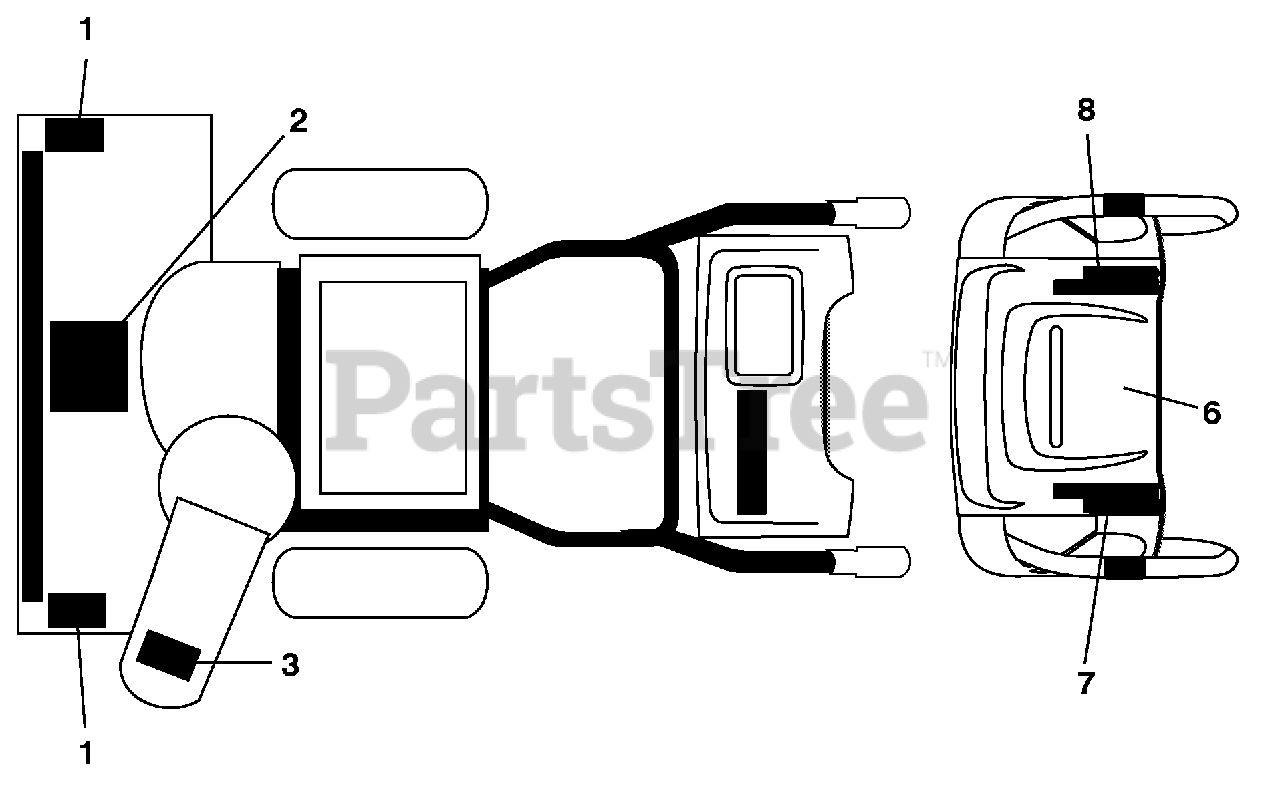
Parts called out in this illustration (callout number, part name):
1	DECAL, DANGER
2	DECAL, DANGER
3	DECAL, DANGER, DEFLECTOR
6	DECAL, INSTRUCTION
7	DECAL, LH TRIGGER
8	DECAL, RH TRIGGER
8	OWNER'S MANUAL, ENGLISH
8	OWNER'S MANUAL, FRENCH
